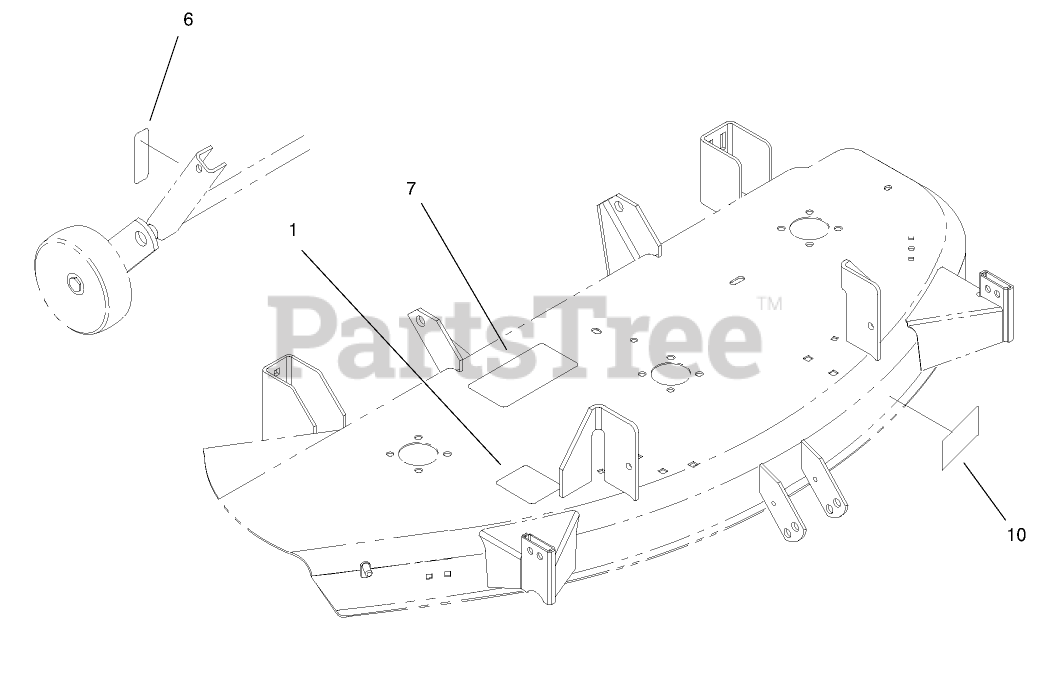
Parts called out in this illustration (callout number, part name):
1	DECAL-BELT ROUTING
6	DECAL-HOC
7	DECAL-BELT ROUTING
10	DECAL-ADJUSTMENT, WHEEL
